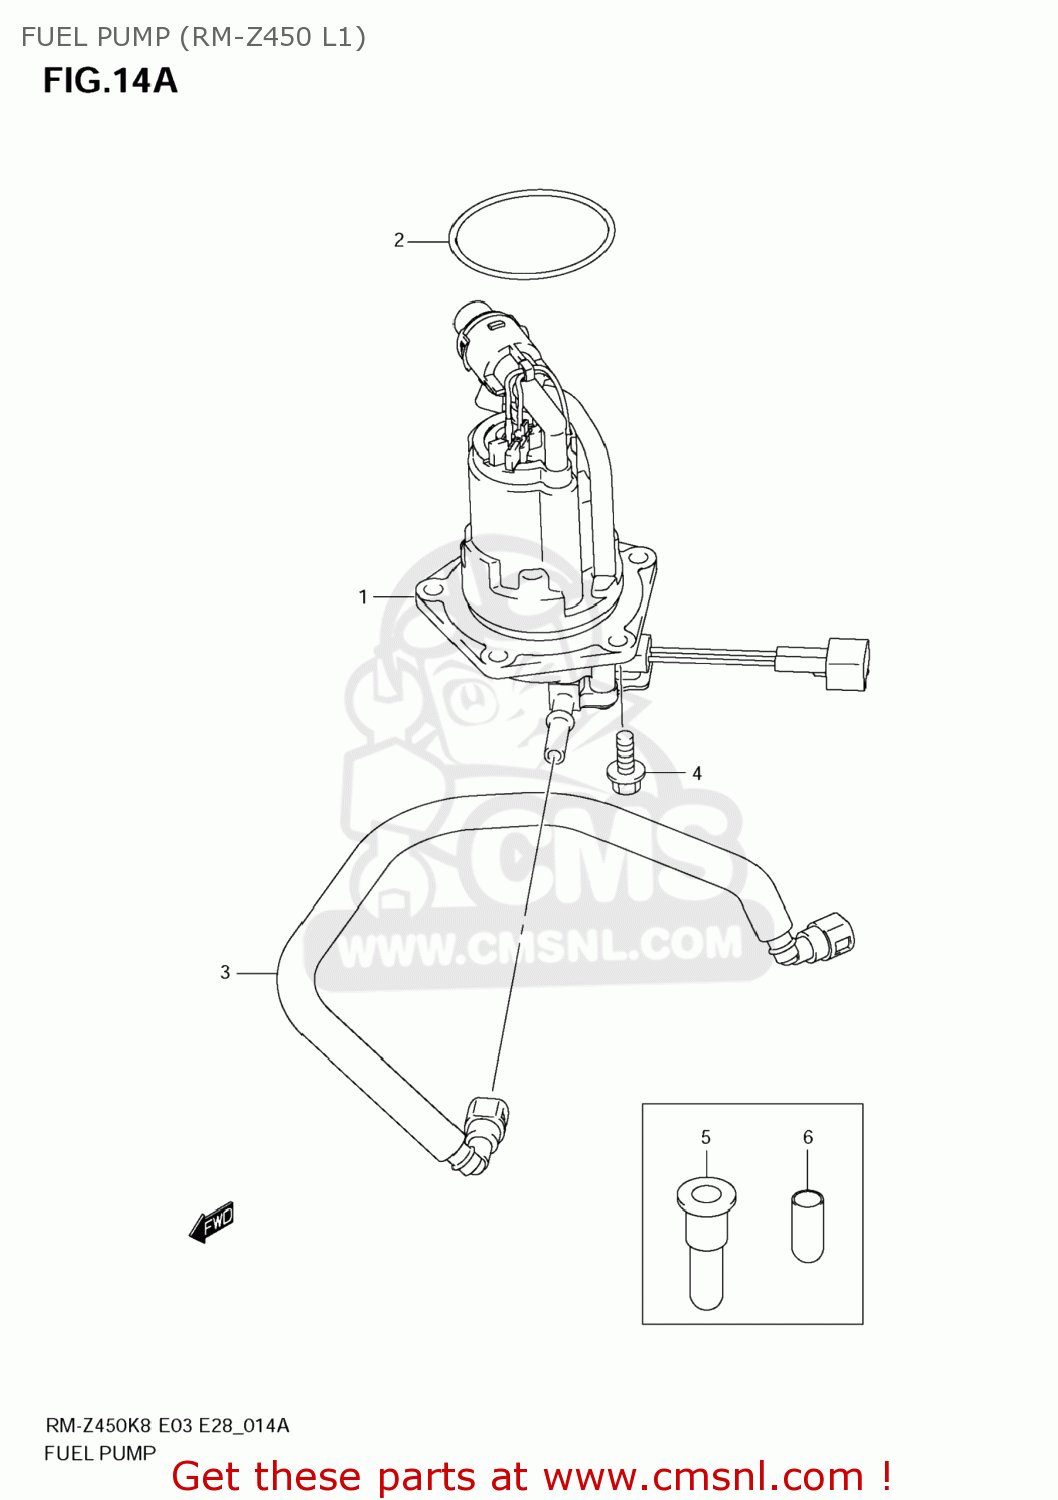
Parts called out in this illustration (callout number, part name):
1	PUMP ASSY,FUEL
2	O RING
3	HOSE,FUEL
4	BOLT
5	CAP,FUEL HOSE
6	CAP,FUEL PUMP
